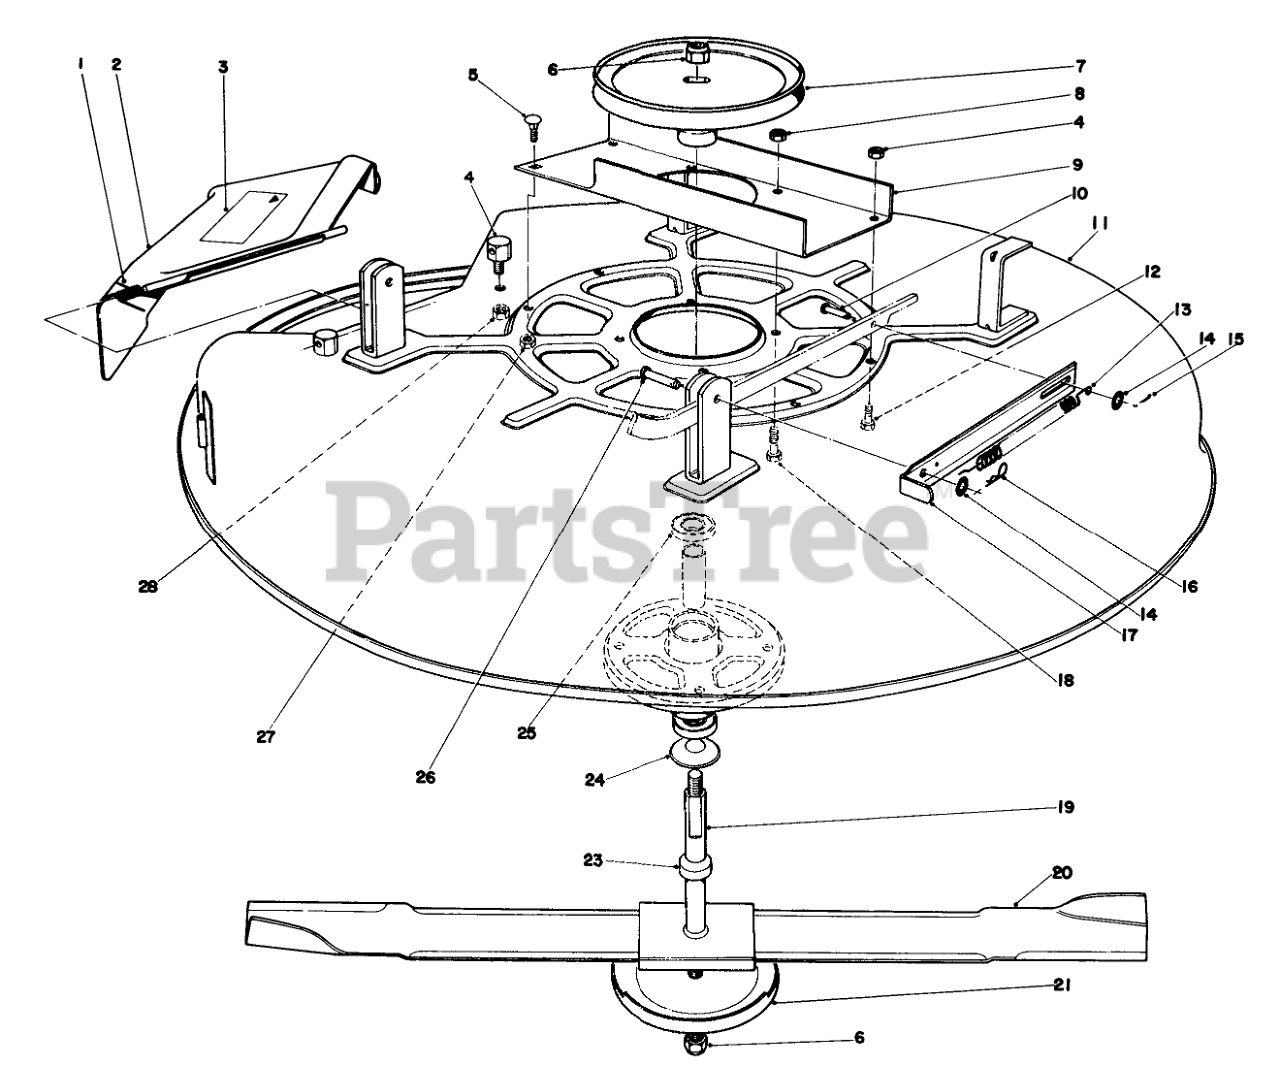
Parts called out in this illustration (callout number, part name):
1	SPRING
2	Deflector Assembly (Incl. Ref. #3)
3	Decal
4	POST-PIVOT
5	SCREW-CARR
7	BLADE DRIVE PULLEY
8	NUT-LOCK, CONE
9	REINFORCEMENT CHANNEL
10	PIN-CLEVIS
11	Cutter Deck
12	SCREW-HH
13	DECK TENSION SPRNG O
14	WASHER-FLAT
15	PIN-COTTER
16	PIN-COTTER
17	Strap-Deck Spring
18	SCREW-HH
19	Spindle Assembly (Incl.Ref. #23-25)
20	Blade
21	Cup
23	SPACER
24	DUST COVER
25	BEARING
26	PIN-CLEVIS
27	NUT-HEX, SIDE DEFORM
28	NUT-LOCK, SIDE
